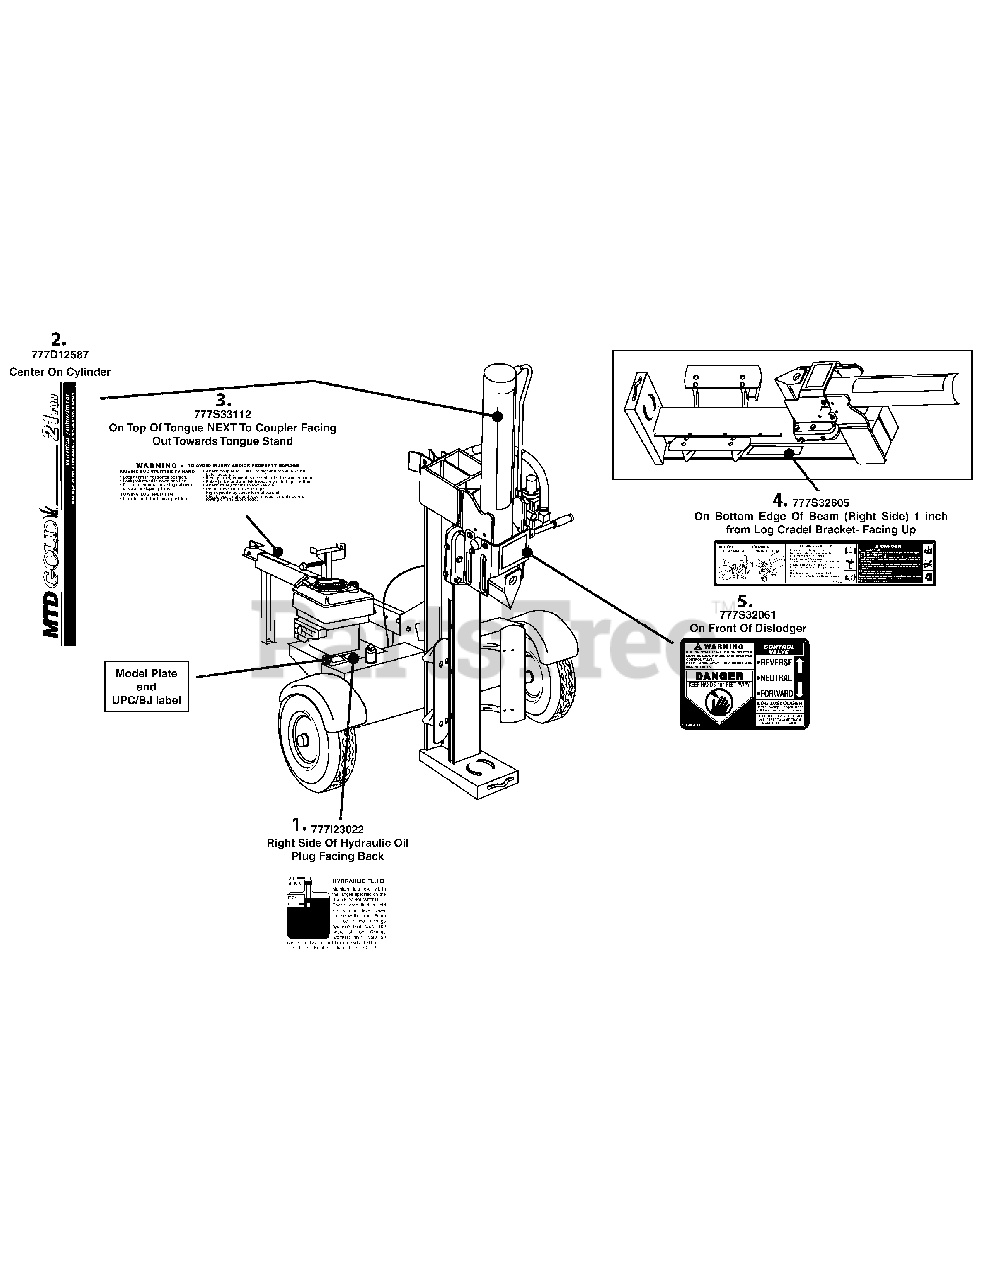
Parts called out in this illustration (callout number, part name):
1	LABEL-LGSPLT:HYRAULICFLUID
2	LABEL-LGSPLTR:CYL:MTD GOLD 21TON
3	LABEL-LGSPLT:MOVNG/TOW:WRNG
4	LABEL-BEAM DNGR INSTR
5	LABEL-CNTRL VALVE
